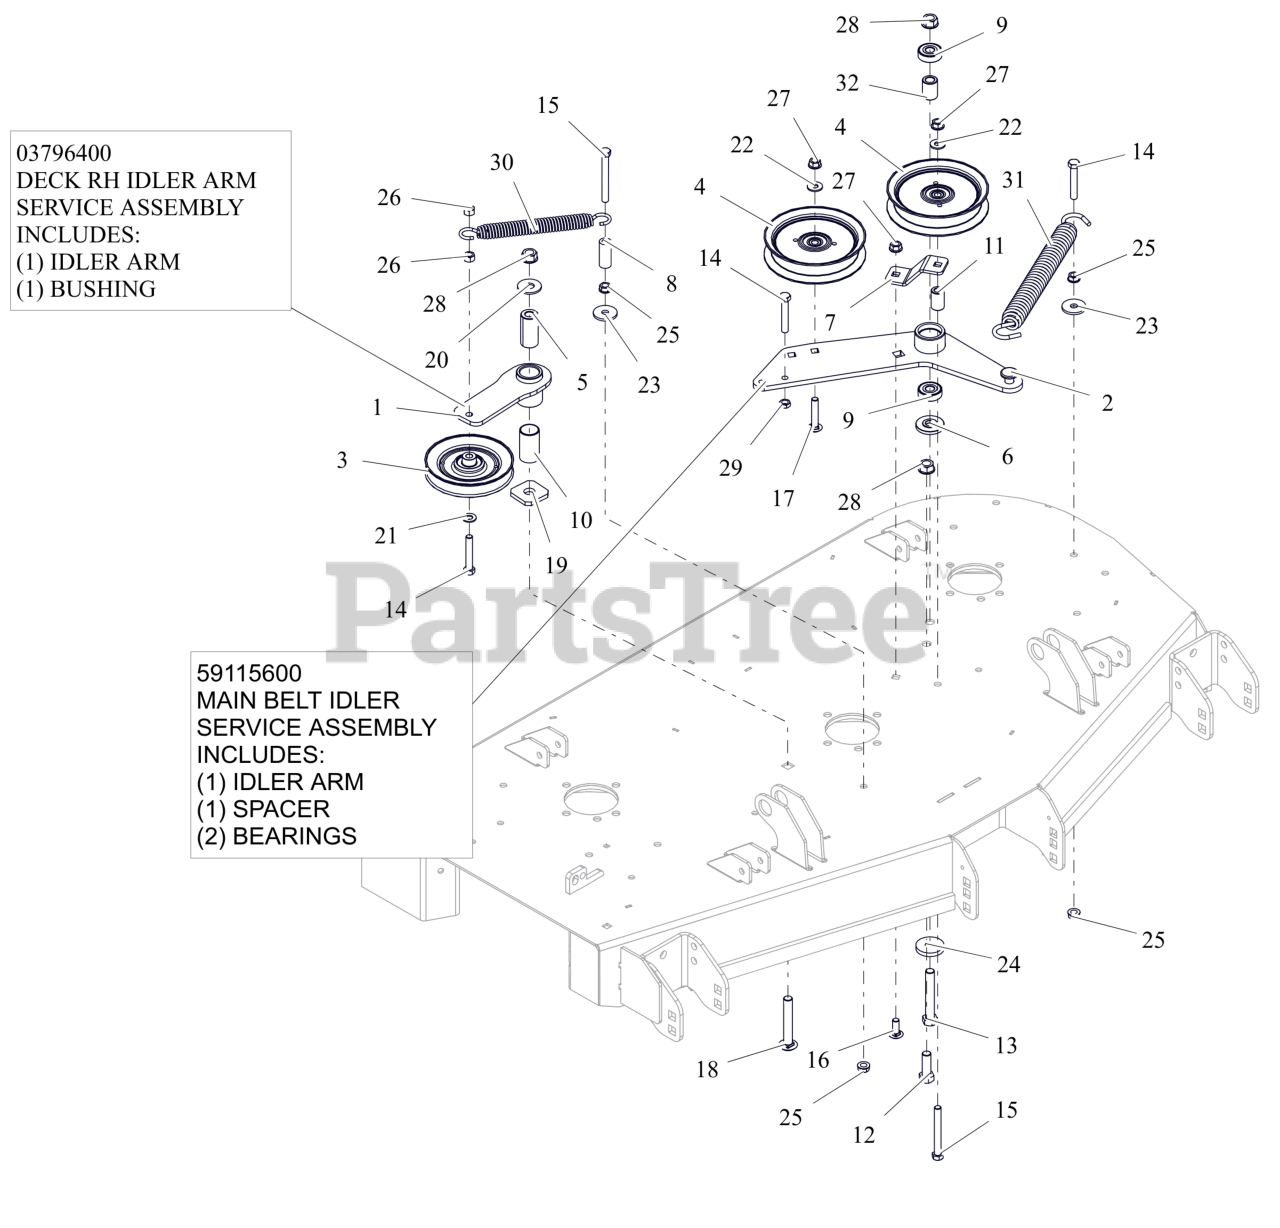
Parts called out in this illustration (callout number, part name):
1	WMT, IDLER ARM - BLACK
1	ASM, IDLER ARM (DECK)
2	WLDMT, DECK PTO IDLR ARM
2	ASSEMBLY, MAIN BELT IDLER
3	IDLER, V-5.00"
4	IDLER, FLAT 5.00"
5	BSHG, SPCR .502X.997X2.03 PM
6	SPACER, IDLER ARM
7	PTO FIXED IDLER MTG BRKT-ORG
8	HOSE, .38 X 1.65
9	BRG-BALL .500X1.38X.437
10	BSHG, 1.00X1.125X1.937
11	BUSHING, SLV .380X.750X1.190
12	BLT,HEX .50-13X1.50 G5 ZCC
13	BLT,HEX .50-13X3.25 G5 ZCC
14	BLT,HEX .38-16X2.25 G5 ZCC
15	BLT, HEX .38-16X3.25 G5 ZCC
16	BLT,RHSSN .38-16X1.00 G5 ZCC
17	BLT,RHSSN.375-16X2.00 G5 ZCC
18	BTL,RHSSN .500-13 X 3.25 G5 ZCC
19	WSHR-FLT .640X1.75X.250
20	WSHR,FLT .563X1.375X.109 ZCC
21	WSHR,FLT .406X.812X.065 ZCC
22	WSHR,FLT .375X.875X.083 ZCC
23	WSHR,FLT .406X1.375X.135 ZCC
24	WSHR-FL-STL 0.557X1.625X0.25 ZCC
25	NUT, SPNLK-FLG .38-16 G5 ZCC
26	NUT-LK-CTR .38-16 ZC120
27	NUT-LK-CTR-FLG .375-16 GF ZCC
28	NUT-LK-CTR-FLG .500-13 GG ZCC
29	NUT-JAM .375-16 G2 ZCC
30	SPRING, EXTENSION
31	SPRING, EXTENSION
32	SPACER .510 X .75 X 1.1485
